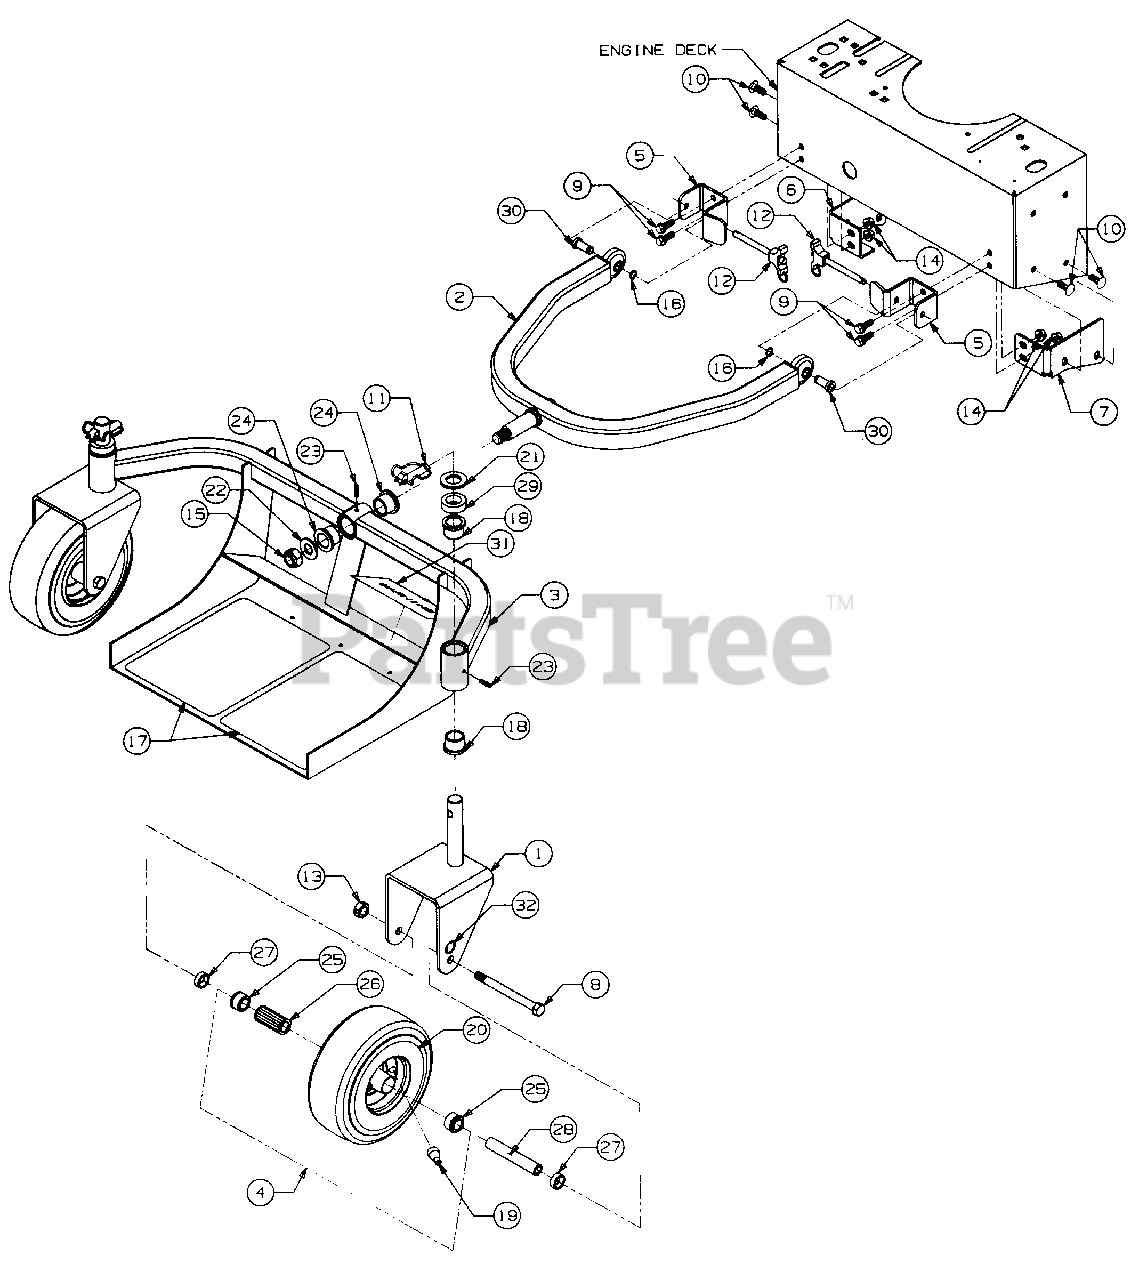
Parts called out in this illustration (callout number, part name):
2	Tubing, A-Frame
7	Bracket, Eng Deck Support RH
8	Screw, Hex Cap, 1/2-20 X 5.50 Lg
9	Screw, Hex Wash TT Tapp, 3/8-16 X 1.0 Lg
10	Bolt, Carriage, 3/8-16 X 1.0 Lg GR5
11	Pin, Klik
12	Pin, Quick Release, 3/8 Dia
13	Nut, Hex Center Lock, 1/2-20
14	Nut, Hex Flanged Lock, 3/8-16
15	Nut, Hex Top Lock, 3/4-16 GR8
16	Ring, Retainer, .50 Shaft
17	Pad, Abrasive Foot
18	Bearing, Flange
19	Valve, Tubeless Air
20	Tire, Smooth, 9.0 X 3.50 X 4
21	Washer, Special
22	Washer, Flat, .750 X 1.50 X .120 Thk
23	Fitting, Lube
24	Bearing, Flange
25	Bearing, Graf Oil Flange
26	Bearing, Roller
27	Spacer, .790 ID X 1.0 OD X .347 Lg
28	Spacer, Wheel
29	Spacer, 1.015 ID X 1.62 OD X .50 Lg
30	Spacer, Shoulder, .378 ID X .50 OD
31	Graphic, Warning
32	Label, Inflation
